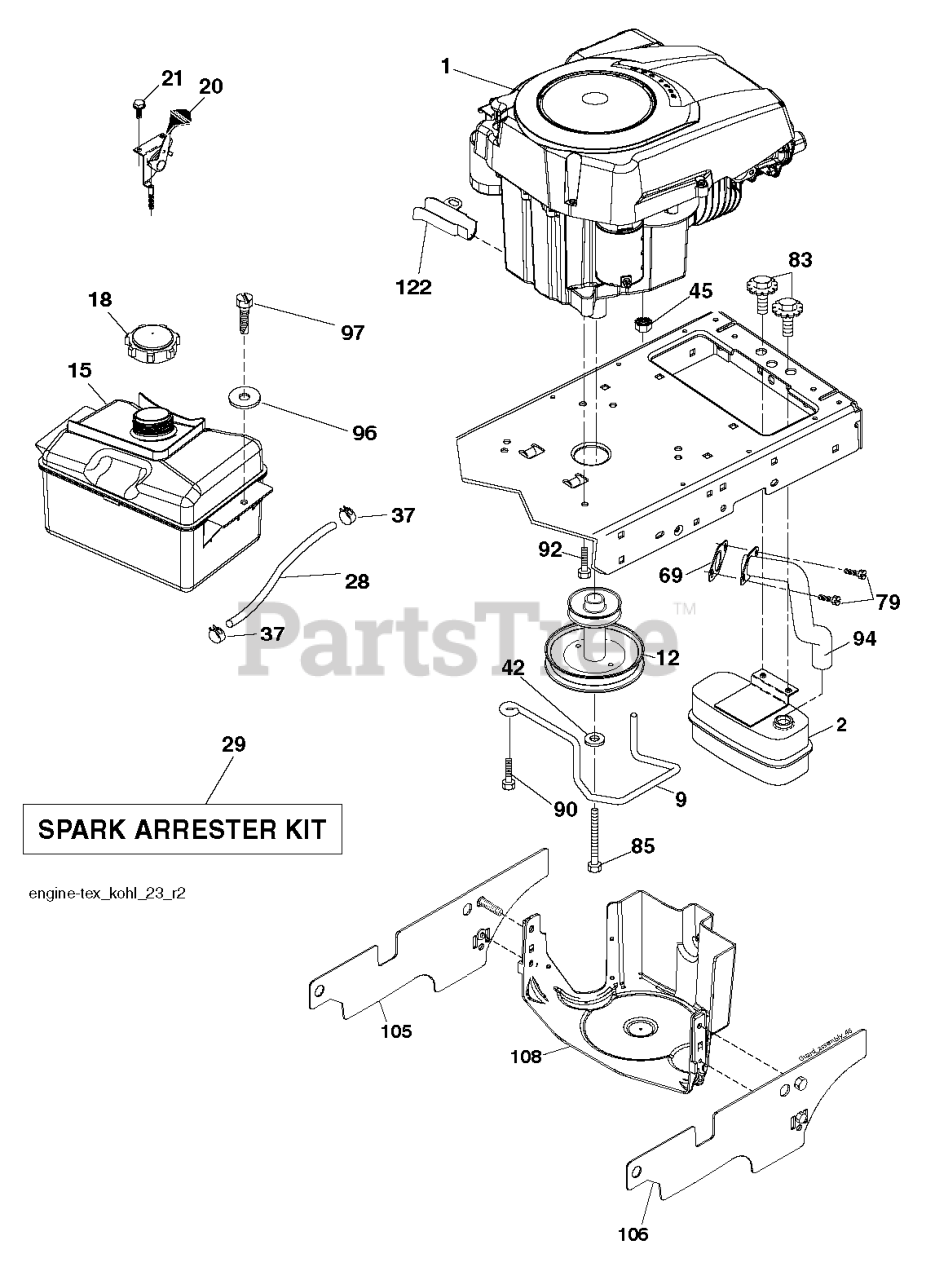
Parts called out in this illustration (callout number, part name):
2	MUFFLER.SINGLE.CYL.KOHL/B&S
9	KEEPER.BELT.ENGINE.4.2
12	PULLY ENGINE
15	RP TANK FUEL FRT 1.5 GAL
18	CAP ASM.FUEL.2.25"FR.
20	CONTROL.TH/CK.C.
21	SCREW.#10 X 0.750.BOS
28	LINE.FUEL.20
29	KIT.SPARK ARRESTOR 794945 B&S
37	HOSE CLAMP
42	LOCKWASHER
45	NUT
69	GASKET.EXHAUST.KOHLER
79	SCREW.SOCKET HD.5/16-1
83	BOLT.5/16-18UNCX3/4 W/SEMS.BLK
85	BOLT HEX 7/16-20X4-1/4"
90	SCREW 3/8-16X1
92	SCREW 3/8-16X1
94	RP.TUBE.EXHAUST.KOHL.COURAGE
97	SCREW HEXWSHR 1/4-20X3/4
108	ENGINE COVER
122	EXTENSION DRAIN OIL
